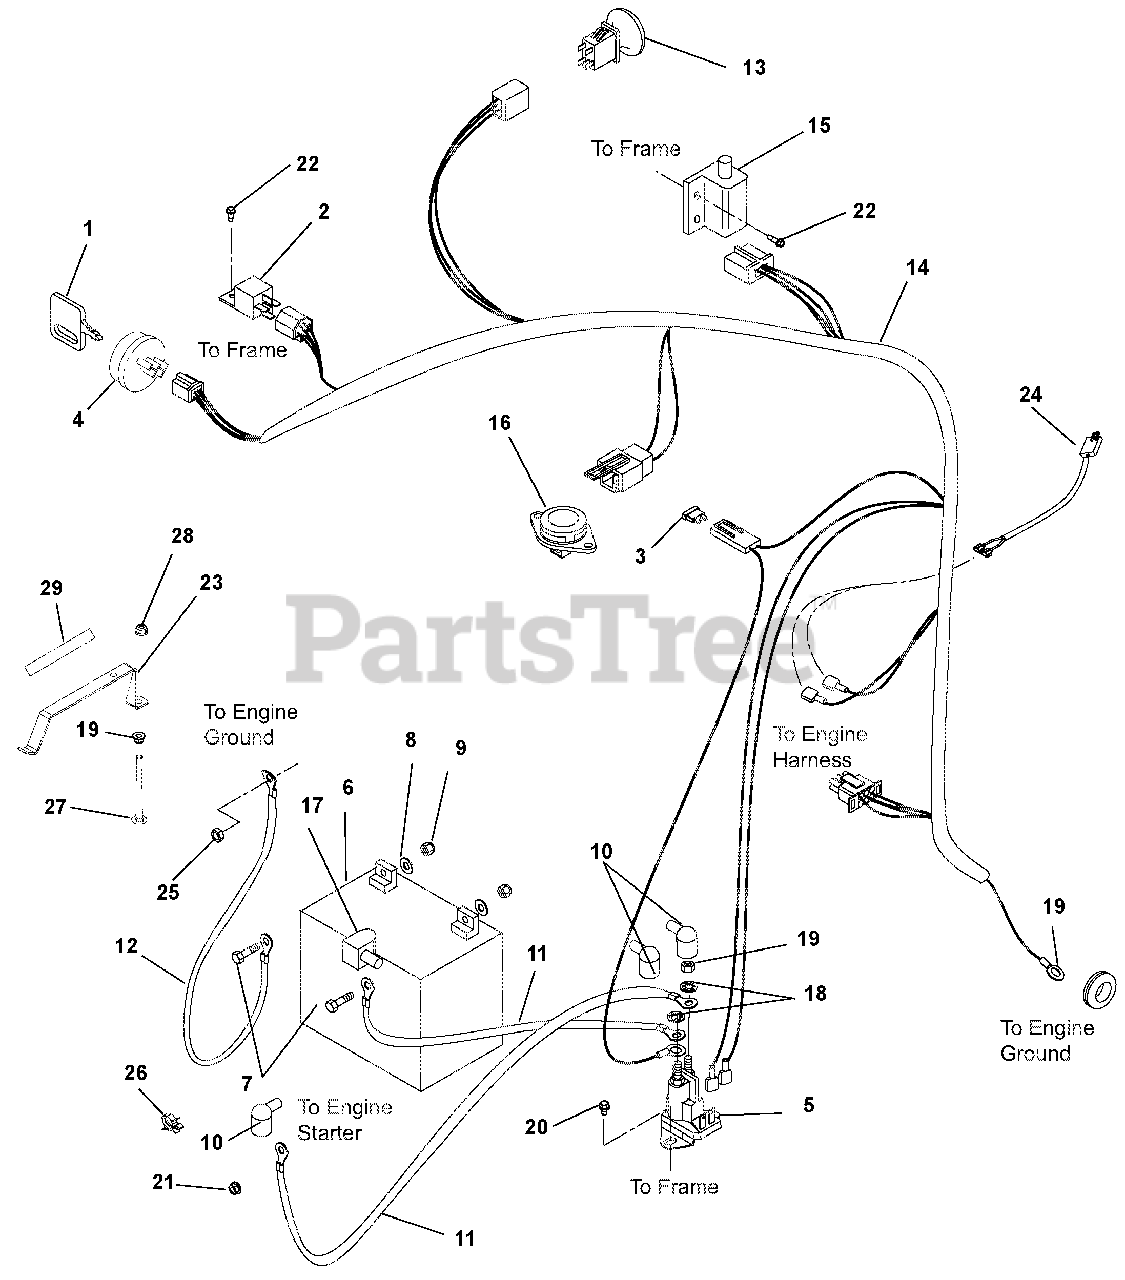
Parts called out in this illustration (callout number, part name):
2	Relay
3	Fuse, 30 AMP
4	KEYSWITCH-IGNITION 3 POS
5	Solenoid, Starter (Sealed)
6	Battery, 12V 20 Hour (Can be replaced with U1 190 or larger)
7	Bolt, Hex .25-20 x .75
8	Washer, Flat Steel .281 x .62 x .065
9	Nut, KEPS .250-20
10	Boot, Eyelet Terminal
11	Cable, POS
12	Ground Cable
13	Switch, Clutch With Retainer
14	Harness, Wiring ZT
15	Switch, Double Pole N.O. / N.O.
16	Switch, Snap Mounting (N.O.)
17	Insulator
18	Washer, Locking .31
19	Nut, Jam .31-24
20	Screw, Tapping .250-20 x .37 Hex Washer Head
21	Nut, Locking Top Flange .25-20
22	Screw, Tapping 10-24 x .50 HWH TR YWZC (Lubricated or Waxed)
23	Hold Down, Battery
24	Harness, Clutch
25	Nut, Locking Center Jam .375-16 (915327)
26	Wire Clip (915328)
27	Bolt, Round Head Square Neck .25-20 x 4.50
28	Nut, Locking Nylon Flange .25-20
29	Decal, U1 Battery Replacement
